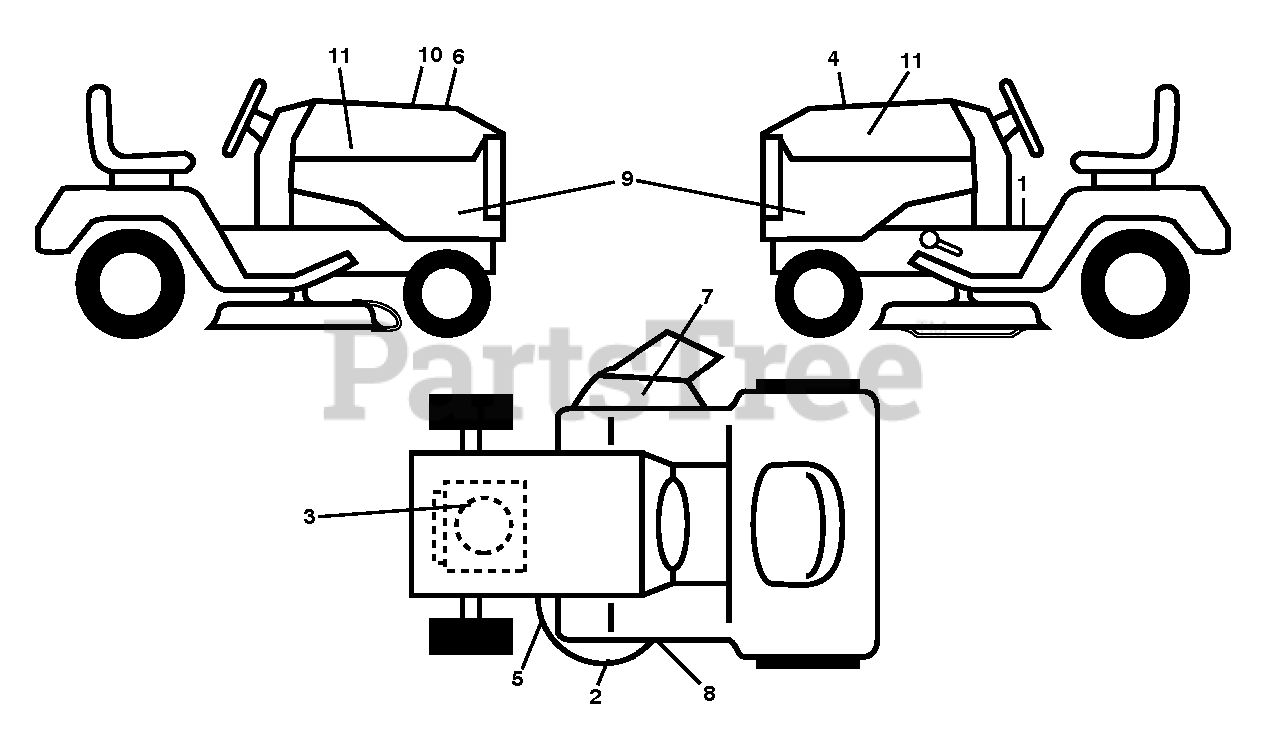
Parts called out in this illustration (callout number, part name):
1	DECAL TRACTOR LOWES DECAL DECA
3	DECAL.ENG.BS.INTK.24HP.382016
4	DECAL.RPL.BSM44.INTK.48.GENTR
5	DECAL.MOWER.CAUTION.TENSION.AR
6	DECAL.E85.WARNING.2012
7	DECAL, DECK DEFLECTOR, WARNING
8	DECAL.MOWER.SCH.48/54.PREM
9	DECAL SIDE PANEL
10	DECAL.WARNING.CUST.RESP.E85.
11	DECAL.BADGE.170MM.TEXTLOGO.
